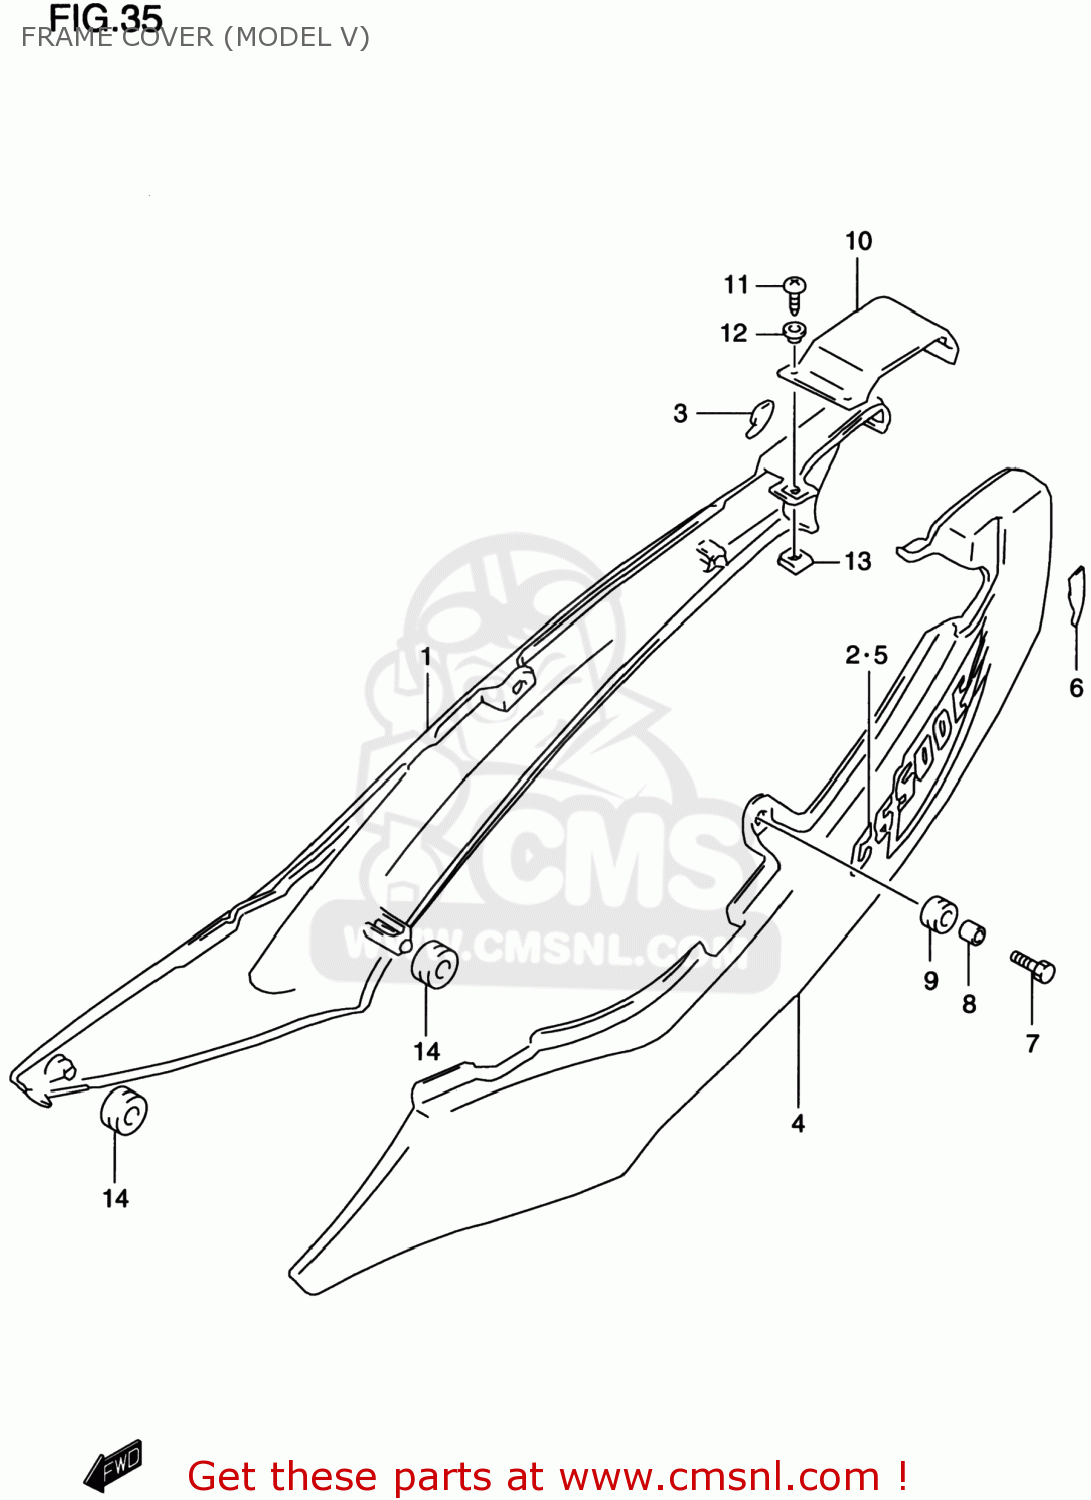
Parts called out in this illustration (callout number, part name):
1	COVER,FRAME,R(BLUE)
2	TAPE,FRAME COVER,R
3	PROTECTOR,FRAME COVER,R
4	COVER,FRAME,L(BLUE)
5	TAPE,FRAME COVER,L
6	PROTECTOR,FRAME COVER,L
7	BOLT(6X20)
8	SPACER(6.5X9X9)
9	CUSHION
10	COVER,FRAME CTR
11	SCREW
12	WASHER(5.2X14X1.5)
13	NUT
14	CUSHION
